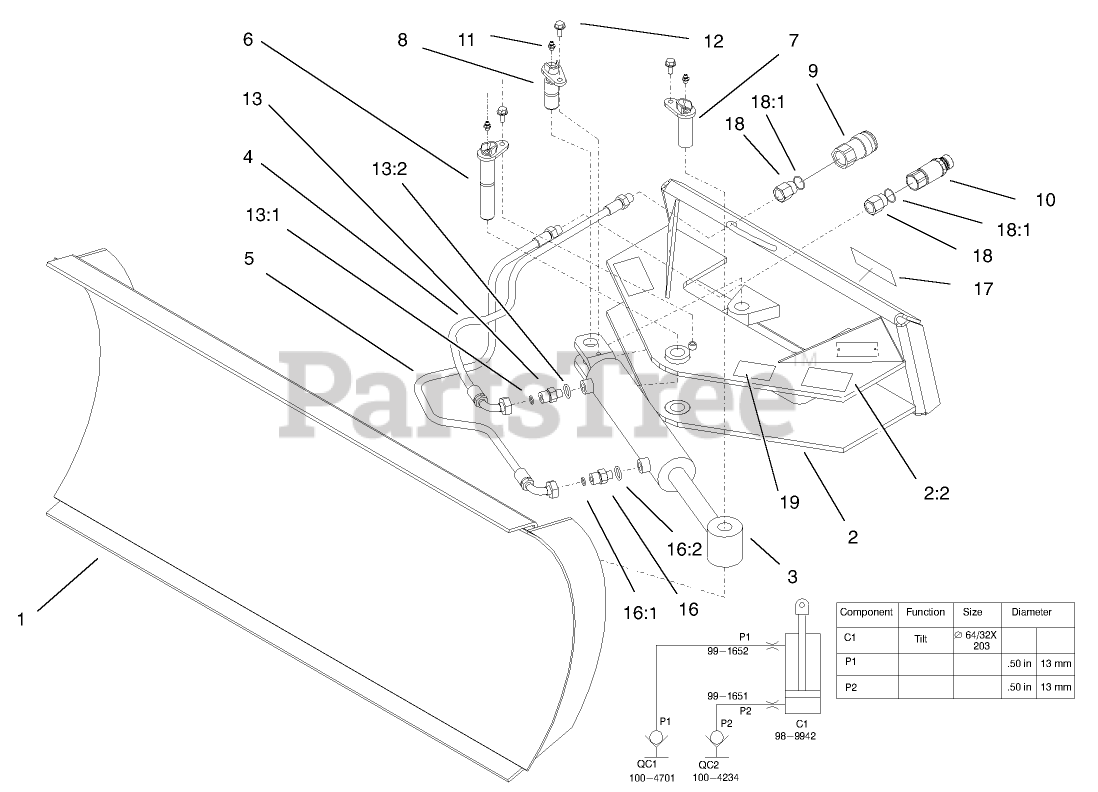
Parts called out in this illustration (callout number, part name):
1	Blade ASM
2	Blade Pivot ASM
2:2	DECAL-WARNING
3	CYLINDER-HYD
4	HYD HOSE ASM
5	HYD HOSE ASM
6	PIN-PIVOT
7	PIN-PIVOT
8	PIN-PIVOT
9	COUPLER-FACE, FLUSH
10	NIPPLE-CONNECT, PRESSURE
11	FITTING-GREASE
12	SCREW-HWHTF
13	FITTING-STR
13:1	O-RING
13:2	O-RING
16	CONNECTOR-STRAIGHT
16:1	O-RING
16:2	O-RING
17	DECAL-ATTACHMENT, DINGO
18	ADAPTER-HYD
18:1	O-RING
19	DECAL
